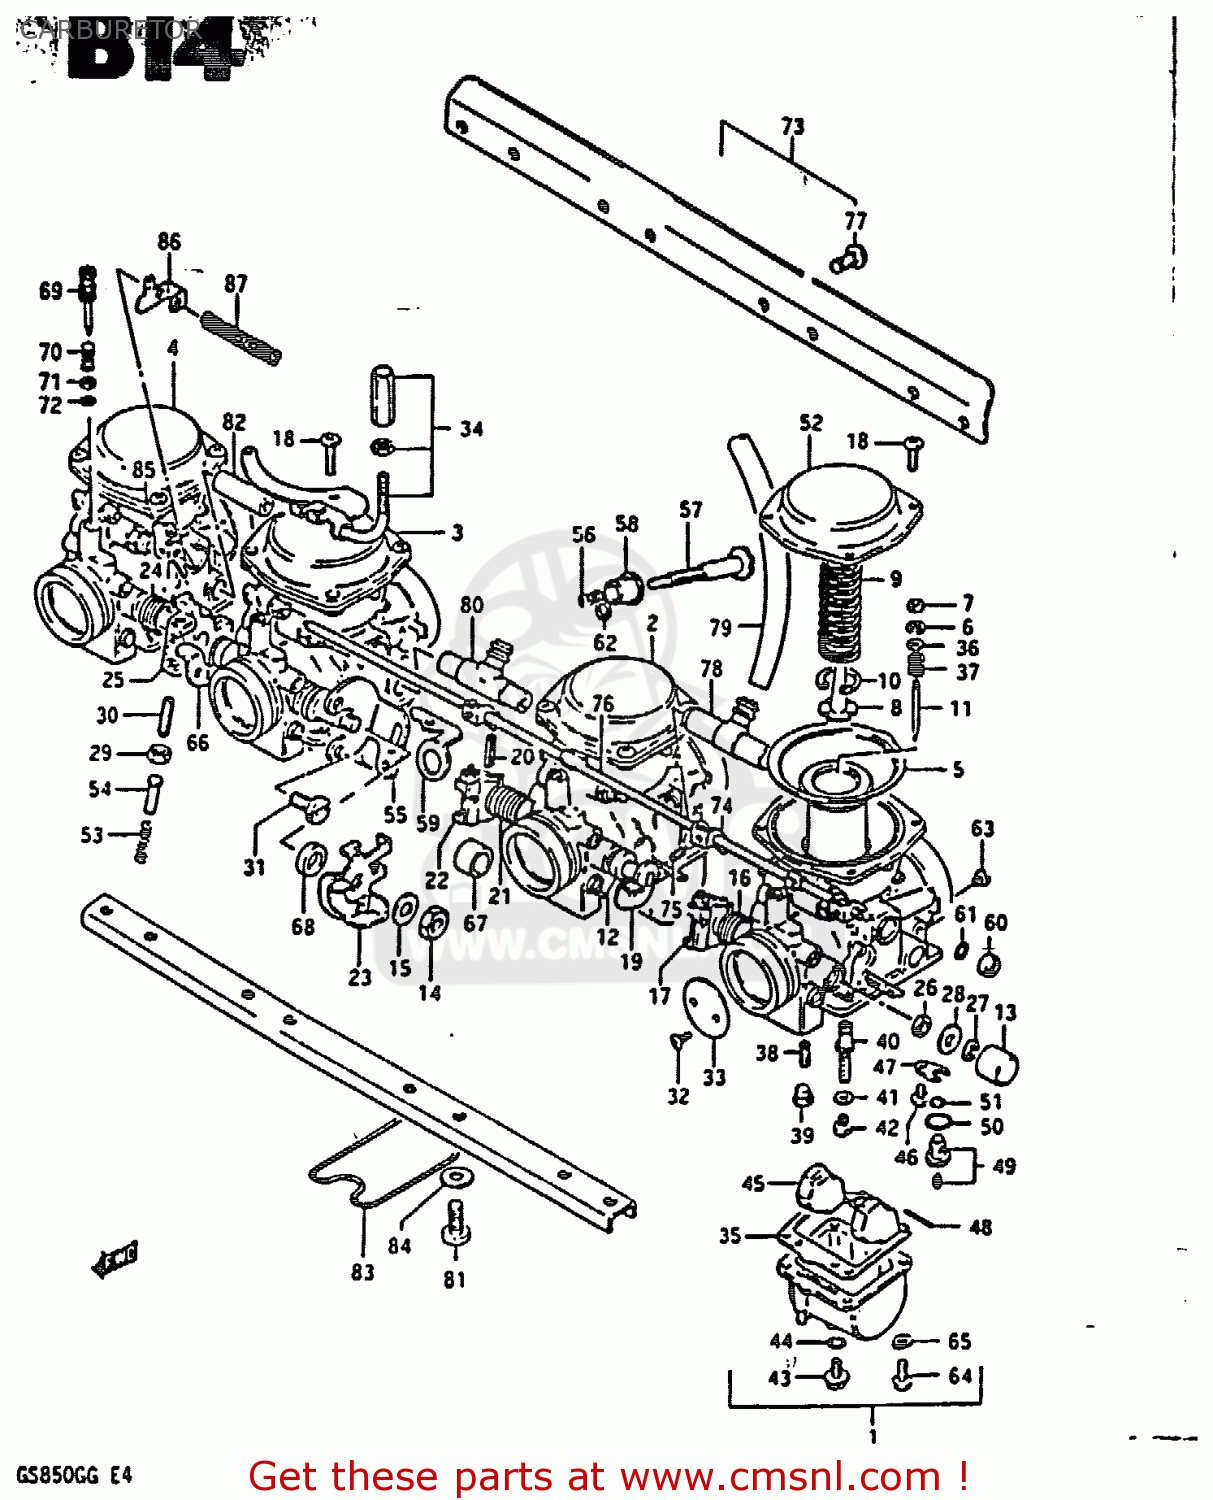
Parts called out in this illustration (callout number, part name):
1	CARBURETOR, NO.1
2	CARBURETOR, NO.2
3	CARBURETOR, NO.3
4	CARBURETOR, NO.4
5	DIAPHRAGM
6	CLIP,NEEDLE
7	RING
8	HOLDER,GUIDE
9	SPRING
10	E RING
11	NEEDLE, JET (5057-2)
12	GASKET,THROTTLE SHAFT (NAS)
13	CAP
14	NUT
15	WASHER
16	SPRING,THROTTLE SHAFT
17	SHAFT,THROTTLE
18	SCREW
19	SHAFT ASSEMBLY
20	PIN,THROTTLE SHAFT
21	SPRING,THROTTLE SHAFT
22	LEVER,THROTTLE SHAFT
23	LEVER ASSEMBLY,THROTTLE
24	SPRING,THROTTLE SHAFT
25	SHAFT,THROTTLE
26	SEAL
27	E RING
28	GASKET,THROTTLE SHAFT (NAS)
29	NUT
30	SCREW
31	SCREW
32	SCREW
33	VALVE,THROTTLE
34	BRACKET,THROTTLE CABLE
35	GASKET,FLOAT CHAMBER (NAS)
36	WASHER
37	SPRING
38	JET,PILOT(42.5)
39	PLUG,NEEDLE JET
40	JET, NEEDLE (X-6)
41	WASHER,NEEDLE NOZZLE
42	JET,MAIN(115)
43	PLUG,DRAIN
44	GASKET (NAS)
45	FLOAT
46	SCREW
47	PLATE,NEEDLE VALVE FITING
48	PIN,FLOAT
49	VALVE ASSY,NEEDLE
50	O-RING,NEEDLE VALVE
51	FILTER
52	COVER,DIAPHRAGM
53	SPRING,THROTTLE SCREW
54	PIN,THROTTLE LEVER
55	BRACKET,THROTTLE ADJUST
56	SPRING
57	SCREW
58	BUSH
59	BRACKET,THROTTLE ADJUST
60	CAP,STARTER VALVE
61	O RING
62	WASHER
63	JET,AIR
64	SCREW
65	LOCK WASHER
66	SHAFT ASSEMBLY
67	RING
68	RING
69	SCREW,PILOT AIR
70	SPRING
71	GASKET
72	O-RING
73	CARBURETOR ASSEMBLY
74	LEVER
75	SCREW
76	SHAFT,STARTER
77	SCREW
78	NIPPLE
79	HOSE,CARBURETOR
80	NIPPLE
81	SCREW
82	NIPPLE
83	CLAMP
84	WASHER
85	LEVER,CHOKE CABLE
86	PLATE,CHOKE CABLE
87	SPRING,CHOKE CABLE
